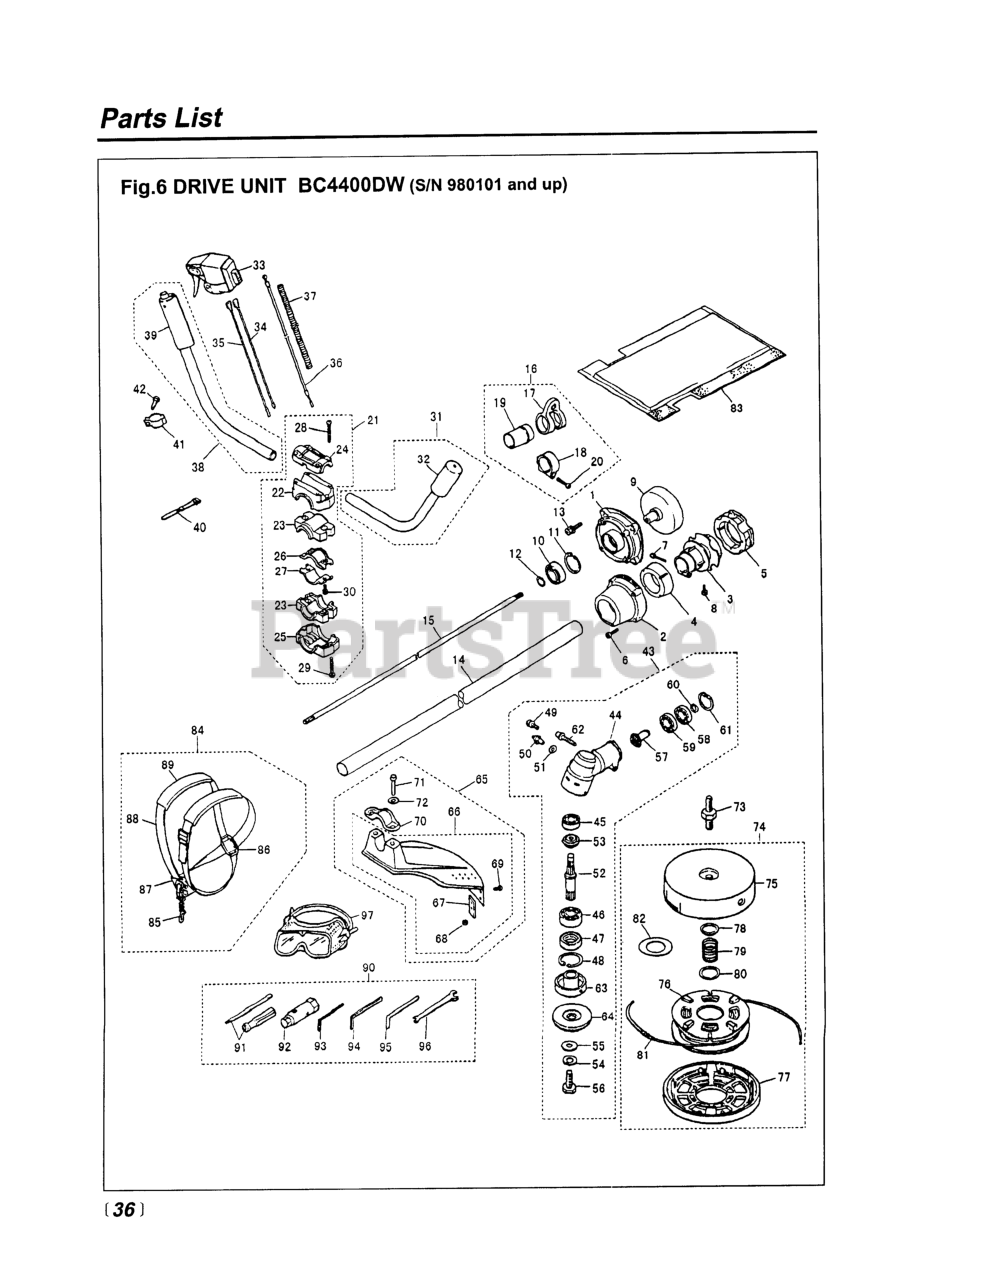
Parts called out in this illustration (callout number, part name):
1	HOUSING
2	CAP
3	JOINT
4	ABSORBER-F
5	ABSORBER-R
6	BOLT, M5 X 30
7	BOLT, M6 x 30
8	BOLT, M5 X 10
10	BEARING
11	RING, SNAP, M35 X 1.5
12	RING, SNAP, M15 X 1.0
13	BOLT, M6 x 20
14	PIPE COMPLETE
15	SHAFT (USE -12212)
16	HANGER ASSEMBLY
17	HANGER
18	CLAMP
20	SCREW, M5 x 25
21	BRACKET ASSY.
22	BRACKET (RPLS -14110)
23	ABSORBER
24	CAP, UPPER (RPLS -14191)
25	CAP, LOWER (RPLS -14120)
26	CLAMP (A)
27	CLAMP (B)
28	BOLT, M5 X 25
29	BOLT, M5 X 35
30	BOLT (USE 3310-31720)
31	HANDLE COMPL, LEFT
33	LEVER ASSEMBLY
34	CORD (A), BLACK
35	CORD (B), RED
37	TUBE
38	HANDLE COMPL, RIGHT
39	GRIP
40	BAND
41	CLAMP
42	SCREW, M5 X 16
44	GEARCASE (RPLS -13113)
45	BEARING (RPLS T3403-13510)
47	SEAL, OIL
48	RING, SNAP, M32 x 1.2
49	BOLT, M5 X 10
50	FITTING, GREASE
51	WASHER, M6 X .8
52	SHAFT
53	GEAR, BEVEL
54	WASHER (RPLS 3180-13270)
55	WASHER, M8 x 2.3 (RPLS -20823)
56	BOLT, LH
57	PINION
59	BEARING (RPLS T3403-13510)
60	RING, SNAP
61	RING, SNAP, M26 X 1.2
62	BOLT, M6 x 1.35
63	HOLDER (A)
64	HOLDER (B)
65	GUARD ASSEMBLY
66	GUARD COMP.
67	BLADE
68	NUT
69	SCREW, M5 x 12
70	CLAMP
71	BOLT, M6 x 1.30
72	WASHER, M6 X 15
73	SHAFT (RPLS 3274-99120)
74	6
75	CASE (USE -99112)
77	COVER
78	PLATE, LARGE
80	PLATE, SMALL
81	CORD
82	SPACER
83	PROTECTOR
87	HANGER COMP.
88	BAND (NOT SOLD SEPARATELY)
89	PROTECTOR
90	TOOL SET
91	SCREWDRIVER
93	WRENCH (TOOL)
94	WRENCH (TOOL)
95	BAR
96	SPANNER, 8 X 10 (RPLS 2540- )
